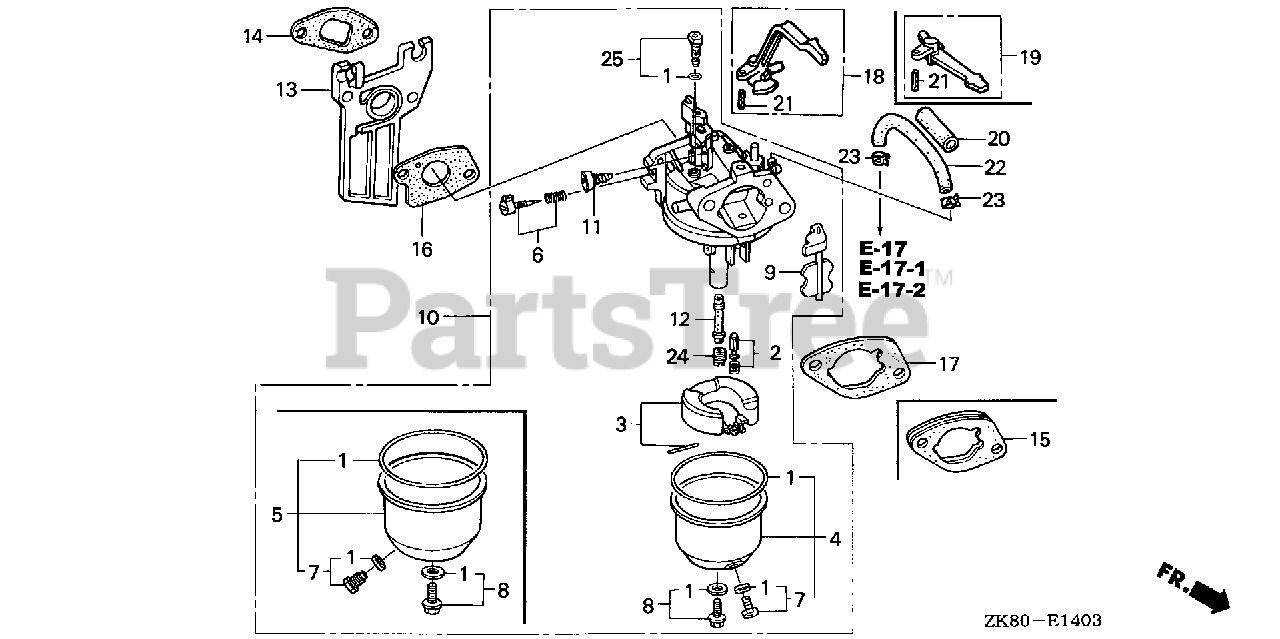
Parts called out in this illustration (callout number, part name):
1	GASKET SET
2	VALVE SET, FLOAT (SEAT NOT INCLUDED)
4	CHAMBER SET, FLOAT
6	SCREW SET, PILOT
7	SCREW SET, DRAIN
8	SCREW SET
10	CARBURETOR ASSY. (BE67A B)
11	SCREW, THROTTLE STOP
12	NOZZLE, MAIN
13	INSULATOR, CARBURETOR
14	GASKET, INSULATOR
16	GASKET, CARBURETOR
17	GASKET, AIR CLEANER
18	LEVER, CHOKE
21	PIN, SPRING (2X12)
24	JET, MAIN (#72)
24	JET, MAIN (#75)
24	JET, MAIN (#70)
25	JET SET, PILOT (#35)
